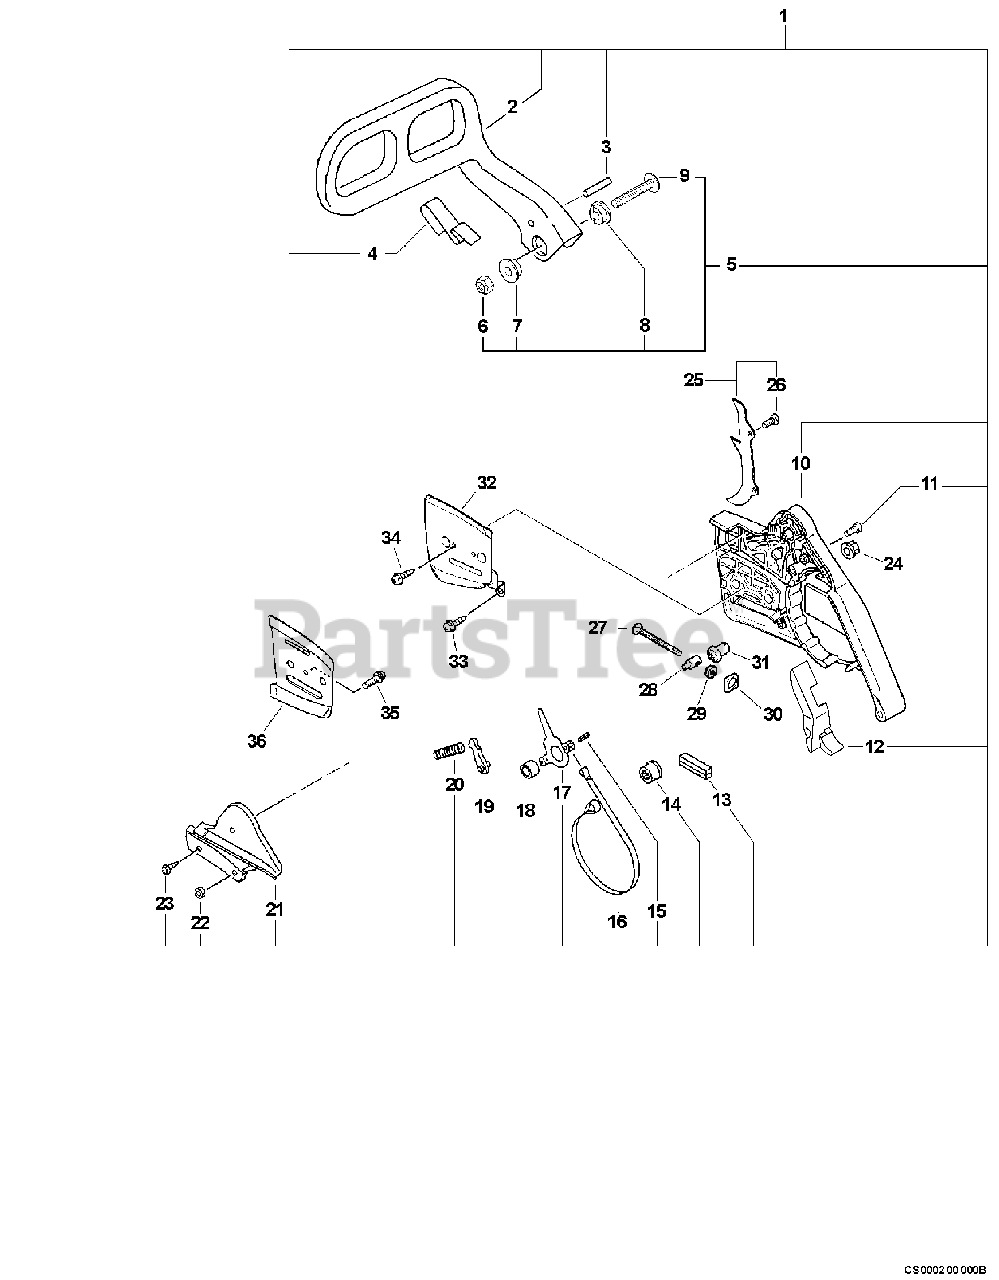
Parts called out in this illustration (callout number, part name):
1	BRAKE ASSY, CHAIN
2	LEVER, BRAKE
3	PIN 3.5×26
4	SPRING, FLAT
5	SCREW KIT
6	NUT, LOCK M5
7	COLLAR 5.3×10×13×L5
8	COLLAR 5
9	SCREW 5×35
10	GUARD KIT, SPROCKET
11	SCREW 3×18
12	CUSHION
13	SEAL, BRAKE
14	ADJUSTER, BRAKE
15	PIN, SPRING 4×8.8
16	BAND, BRAKE
17	LEVER, BRAKE
18	SPACER 8×12×9
19	STOPPER, BRAKE
20	SPRING, BRAKE
21	COVER, BRAKE
22	NUT 3 MM
23	SCREW 4×12
24	NUT, FLANGE M8×1.25
25	SPIKE KIT, BUMPER
26	BOLT 5×12
27	SCREW, CHAIN TENSION
28	TENSIONER, CHAIN
29	GEAR, BEVEL
30	COLLAR 8
31	GEAR, BEVEL
32	PLATE, GUIDE - OUTER
33	SCREW 4×10
34	SCREW 3×6
35	SCREW 4×8
36	PLATE, GUIDE - INNER
